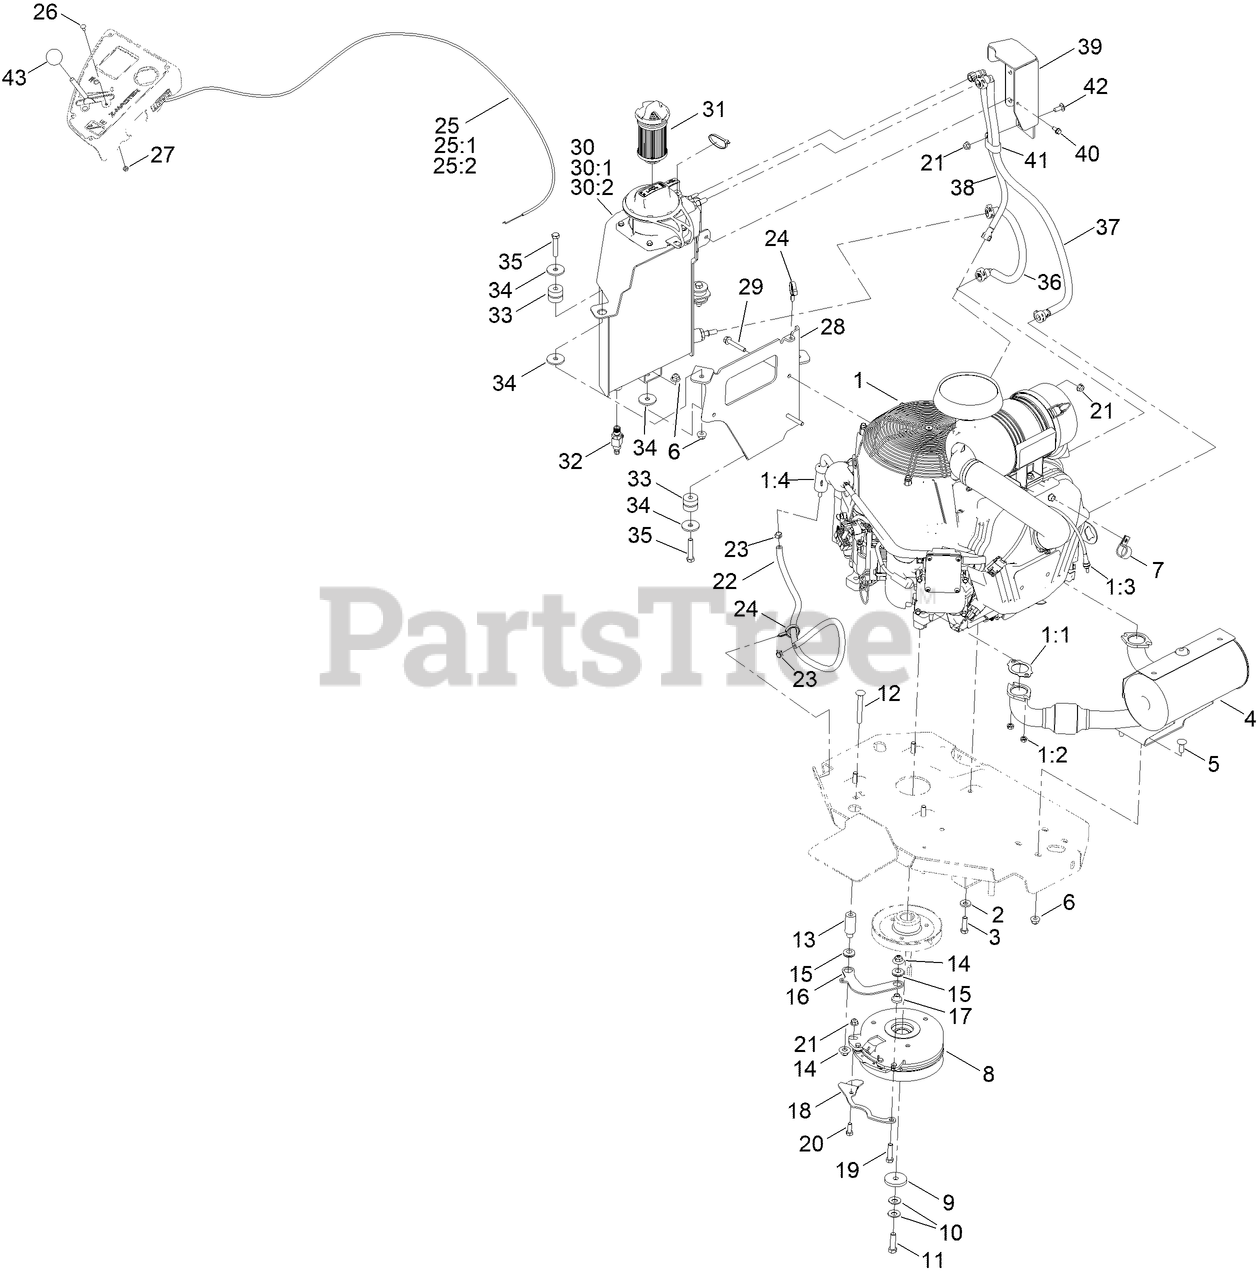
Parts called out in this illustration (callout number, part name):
1	ENGINE-VANGUARD
1:1	GASKET-EXHAUST
1:2	NUT-HEX
1:3	SENSOR-O2
1:4	FILTER-FUEL
2	WASHER-BELLEVILLE
3	SCREW-HH
4	MUFFLER
5	SCREW-CARR
6	NUT-HF, NI
7	R-CLAMP
8	CLUTCH KIT
9	WASHER-CLUTCH
10	WASHER-SPRING
11	SCREW-HH, W/LOCTITE
12	SCREW-CARR
13	SPACER
14	NUT-FLANGE, NI
15	GROMMET-RUBBER
16	LINK-ANCHOR, CLUTCH
17	SPACER
18	BELT-GUIDE
19	SCREW-HH
20	SCREW-HH
21	NUT-HF, NI
22	HOSE-FUEL
23	CLAMP-HOSE
24	CLAMP-HOSE
25	THROTTLE CONTROL ASM
25:1	LEVER-THROTTLE
26	BOLT-CARR
27	NUT-LOCK, NI
28	MOUNT-TANK, OIL
29	SCREW-HHF
30	RESERVOIR-OIL
30:1	OIL DIPSTICK ASM
30:2	OIL TANK CAP ASM
31	FILTER-OIL
32	VALVE-OIL DRAIN
33	ISOLATOR-TANK
34	WASHER
35	SCREW-HH
36	HOSE-SUPPLY
37	HOSE-SCAVENGE
38	HOSE-VENT
39	GUARD-HOSE
40	SCREW-HWH
42	SCREW-CARR
43	KNOB-BALL
